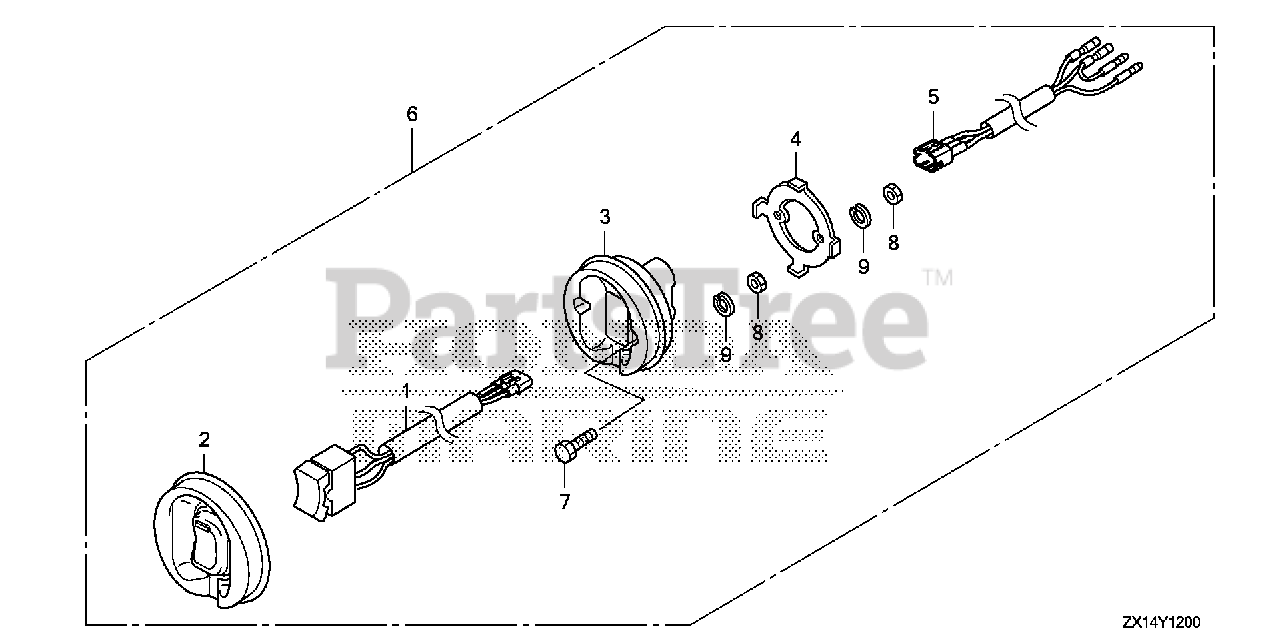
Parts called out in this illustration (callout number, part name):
1	SWITCH ASSY., TROLLING CONTROL (ENGINE NO.)
2	RUBBER, TROLLING CONTROL SWITCH PANEL (ENGINE NO.)
3	BODY, TROLLING CONTROL SWITCH PANEL (ENGINE NO.)
4	BRACKET, TROLLING CONTROL SWITCH PANEL (ENGINE NO.)
5	HARNESS, TROLLING CONTROL SWITCH PANEL (ENGINE NO.)
6	PANEL ASSY., TROLLING CONTROL (ENGINE NO.)
7	BOLT, HEX. (4X20) (ENGINE NO.)
8	NUT, HEX. (4MM) (ENGINE NO.) (NOT AVAILABLE)
9	WASHER, SPRING (4MM) (ENGINE NO.)
